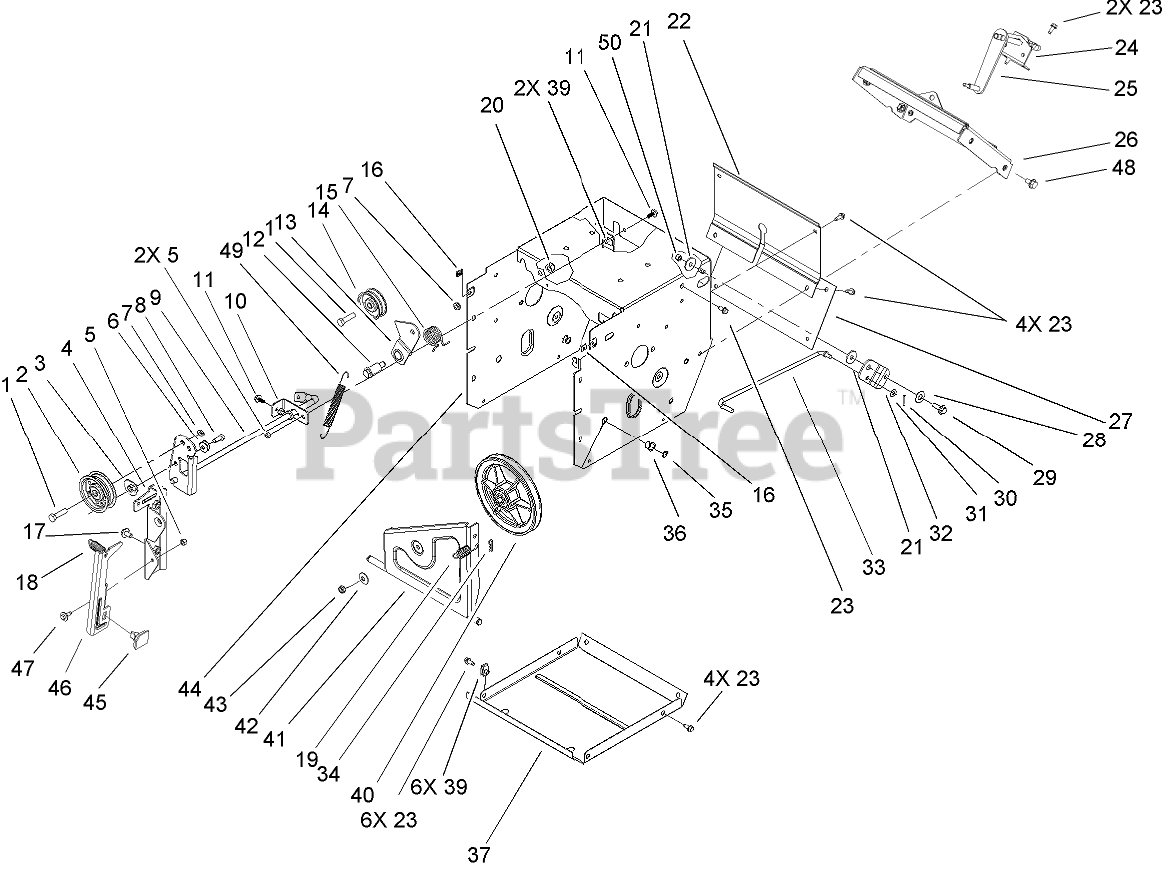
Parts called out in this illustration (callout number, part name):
1	SCREW-HH
2	PULLEY-IDLER
4	BRACKET-IDLER, IMPELLER
5	NUT-LOCK, NI
6	WASHER-BELLEVILLE
7	NUT-LOCK, NI
8	SCREW-HH
9	IMPELLER CLUTCH ASM
10	BRACKET-REAR, CLUTCH
11	SCREW-HHF
12	BOLT-SHOULDER
13	ARM-IDLER, TRACTION
14	PULLEY-IDLER
15	SPRING-TORSION
16	NUT-SPEED, U-TYPE
17	SCREW-HHF
18	SPRING-EXTENSION
19	SPRING-EXTENSION
20	NUT-LOCK, NI
21	WASHER-PIVOT
22	COVER-UPPER
23	SCREW-HWH
24	BRACKET-ROD, SHIFT
25	LEVER-CONTROL, TRACTION
26	SHIFT PLATE ASM
27	COVER-LOWER
28	WASHER
29	SCREW-SHOULDER
30	PIN-COTTER
31	WASHER-PLAIN
32	BELLCRANK-DRIVE
33	LINK-CONTROL, SPEED
34	PIN-COTTER
35	RING-RETAINING
36	BUSHING-NYLINER
37	PAN-BOTTOM
40	PULLEY-TRACTION
41	PULLEY PIVOT ASM
42	WASHER-BELLEVILLE
43	NUT-HEX
44	TRACTION FRAME ASM
45	PAD-BRAKE
46	ARM-BRAKE
47	SCREW-SHOULDER
48	SCREW-HWHTF
49	SPRING-EXTENSION
50	NUT-LOCK, NI
